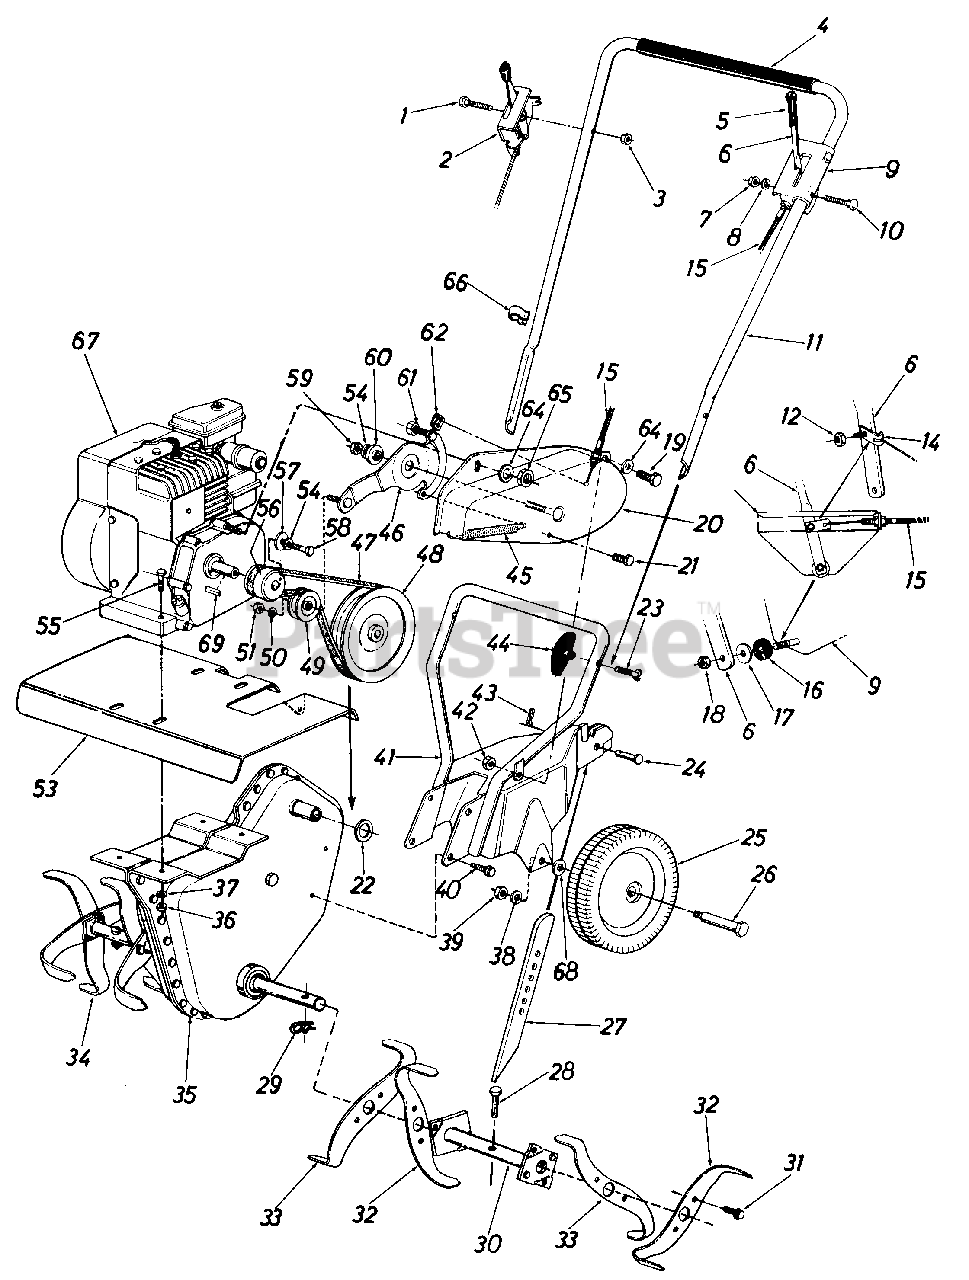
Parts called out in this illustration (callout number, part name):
1	Hex Bolt 1/4-20 x 1.50" Lg.
2	Throttle Control Ass'y. Comp.
3	Hex Cent. L-Nut 1/4-20 Thd.
4	Grip - 12" Lg.
5	Handle Grip
6	Clutch Handle Ass'y.
7	Hex Cent. L-Nut 1/4-20 Thd.
8	Fl-Wash. 1/4" I.D. x .50" O.D. x .063
9	Clutch Handle Brkt. Ass'y.
10	Carr. Bolt 1/4-20 x 1.25" Lg.
11	Upper Handle
12	Hex Cent. L-Nut 1/4-20 Thd.
15	Clutch Cable
16	Rubber Wash.
17	Fl-Wash. 1/4" I.D. x .75" O.D. x .063
18	Hex Cent. L-Nut 1/4-20 Thd.
19	Hex Bolt 1/4-20 x .50" Lg.
20	Belt Cover Ass'y.
21	Hex Wash. Hd. Tap Scr. 1/4 x .50"
22	Fl-Wash. .52 I.D. x 1.00 O.D. x .050
23	Curved Hd. Bolt 5/16-16 x 1.75" Lg.
24	Clevis Pin
25	Wheel Ass'y.
26	Shoulder Bolt
27	Depth Bar
28	Clevis Pin .31 Dia. x 1.50" Lg.
29	Hairpin Cotter
34	Tine Ass'y. Comp.
35	Chain Case Ass'y. Comp.
36	Hex Nut 5/16-18 Thd.
37	L-Wash. 5/16" Scr.
38	L-Wash. 3/8" Scr. H.D.
39	Hex Cent. L-Nut 3/8-16 Thd.
40	Hex Wash. SF-Tap Scr. 5/16-18 x .50" Lg.
43	Intern. Cotter Pin
44	Hand Knob
45	Extension Spring .60 O.D. x 4.88" Lg.
46	Idler Arm Ass'y.
47	Belt 3/8" x 29" Lg.
48	Chain Case Pulley 5 1/2 x 1/2"
49	Fl-Idler 2"
50	L-Wash. 5/16" Scr.
51	Hex Nut 3/8-24 Thd.
55	Hex Bolt 5/16-18 x 1.50" Lg.
56	Engine Pulley 3/8 V x .7525 I.D. x 2" O.D.
57	Fl-Wash. .385 I.D. x 1.00" O.D. x .135
58	Hex Bolt 3/8-24 x 1.00" Lg.
59	Hex Nut 5/16-18 Thd."
60	Shld. Spacer .50" Dia. x .133
61	Hex Cent. L-Nut 1/4-20 Thd.
64	Fl-Wash. .281" I.D. x .500" O.D. x .063
65	Hex Cent. .L-Nut 1/4-20 Thd.
66	Cable Clip
67	Engine
68	Bell-Wash.
69	Square Key 3/16 x 3/4" Lg.
